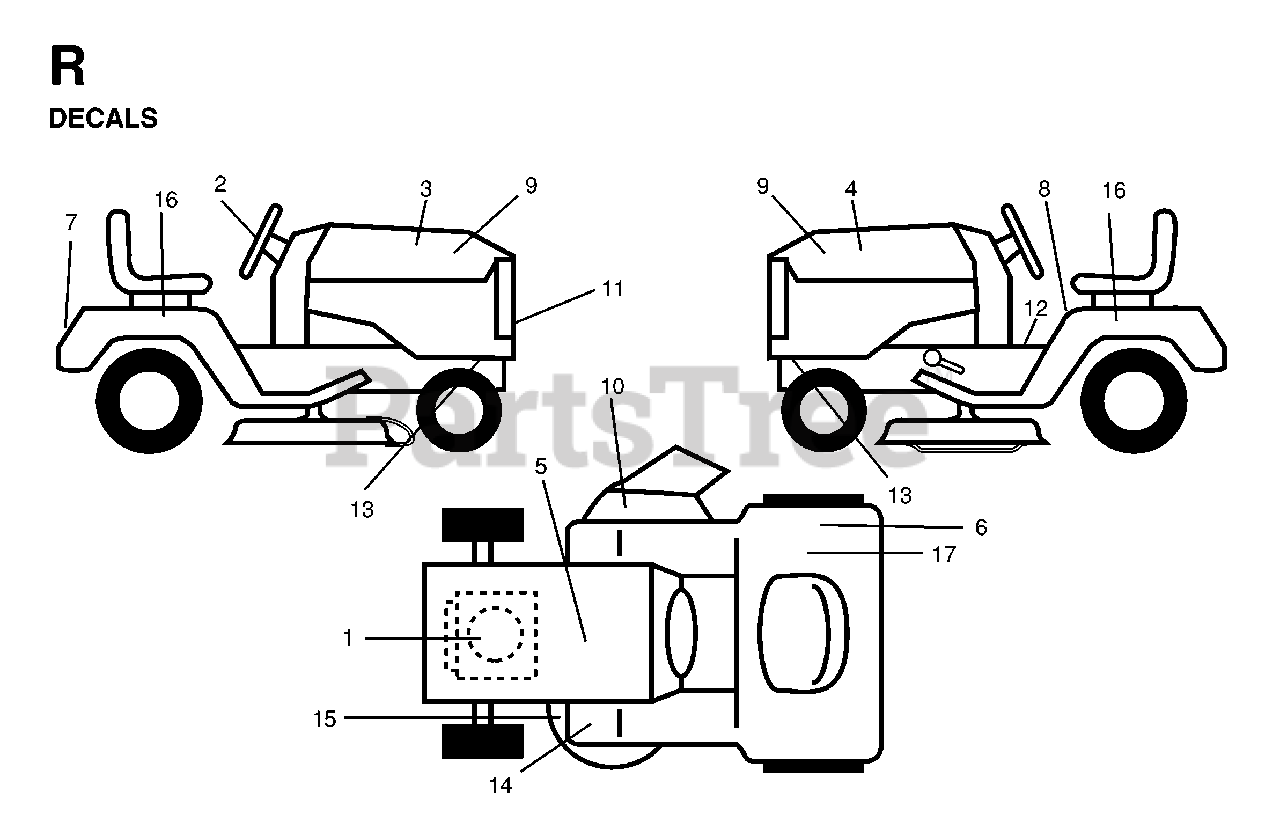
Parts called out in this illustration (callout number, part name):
5	DECAL BTRY SYMBOLS
6	DECAL CERTIFICATION
8	DECAL READ OWNER'S MAN SYMS
10	DECAL MOWER CUT/FINGER
12	DECAL PARK BRAKE
15	DECAL V BELT SCHEMATIC
17	DECAL EUROPE STANDARD CE
